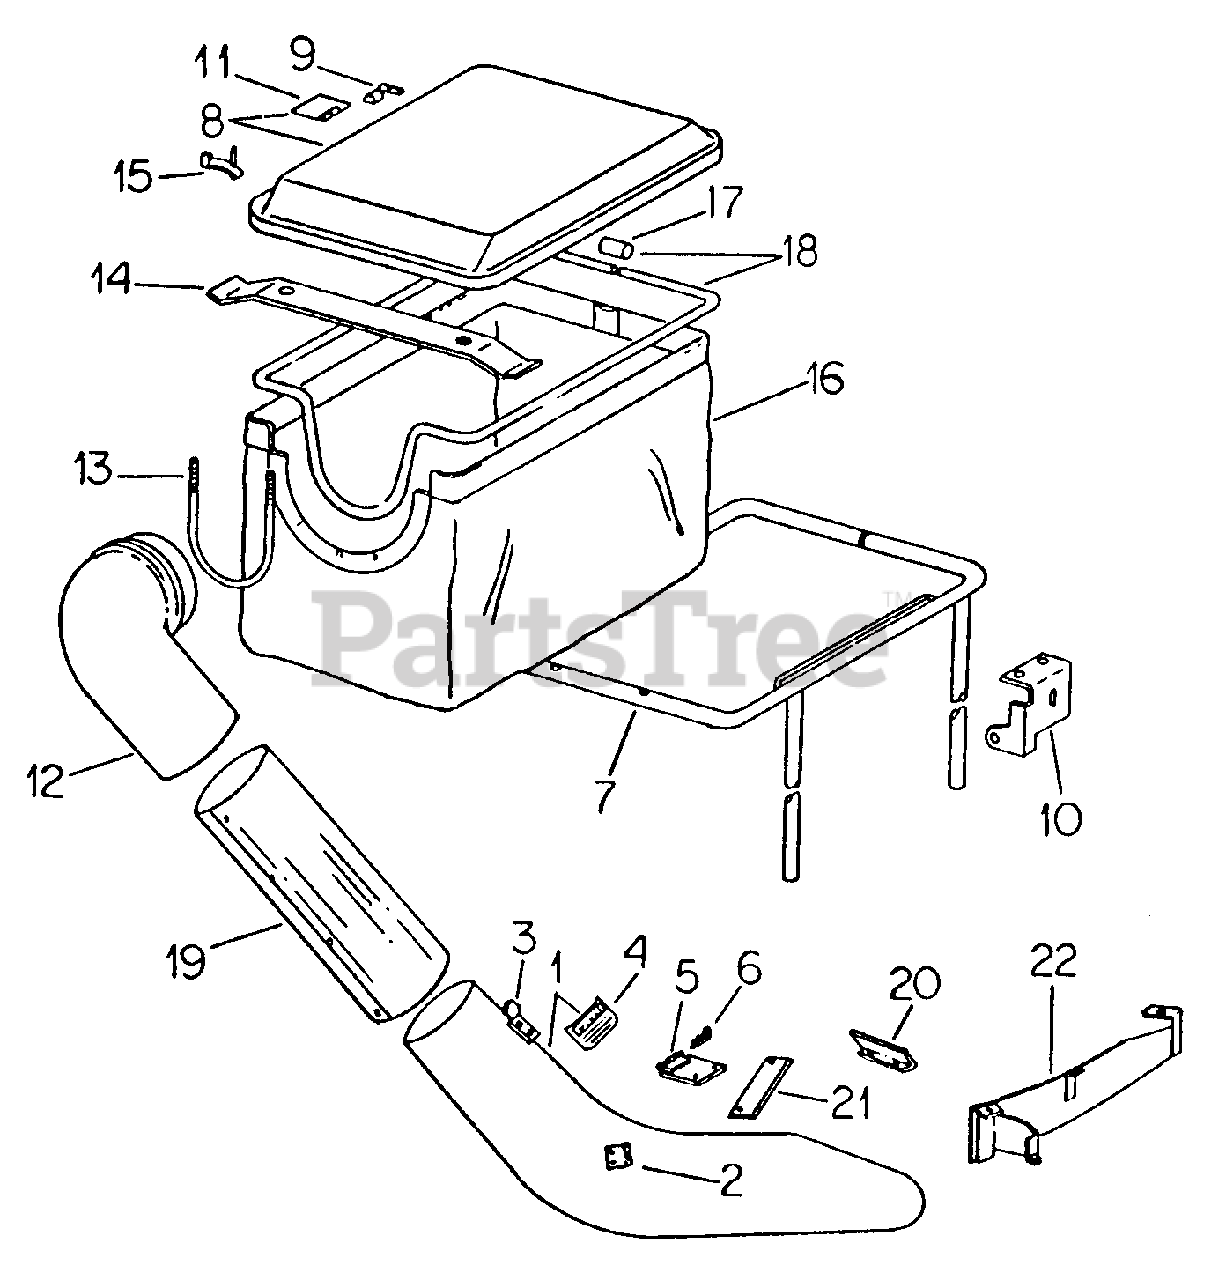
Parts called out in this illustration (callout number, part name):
1	Chute Assy, Discharge
2	Hinge, Chute
3	Retainer, Tube
4	Product Graphic, Caution
5	Hinge Assy, Chute
6	Pin, Quick Attachable Cot Cdp
7	Frame Assy, Bagger
8	Cover Assy, Grass Bag
9	Clip, Cover
10	Support, Cover
11	Product Graphic, Caution
12	Elbow, Chute
13	Bracket, Elbow
14	Spring, Bag Retainer
15	Catch Assy
16	Bag, Grass
17	Sleeve, Bag Frame
18	Frame, Bag
19	Sheet, Connecting Tube
20	Impeller, 36 Inch Mower Blade
21	Flange, Locator
